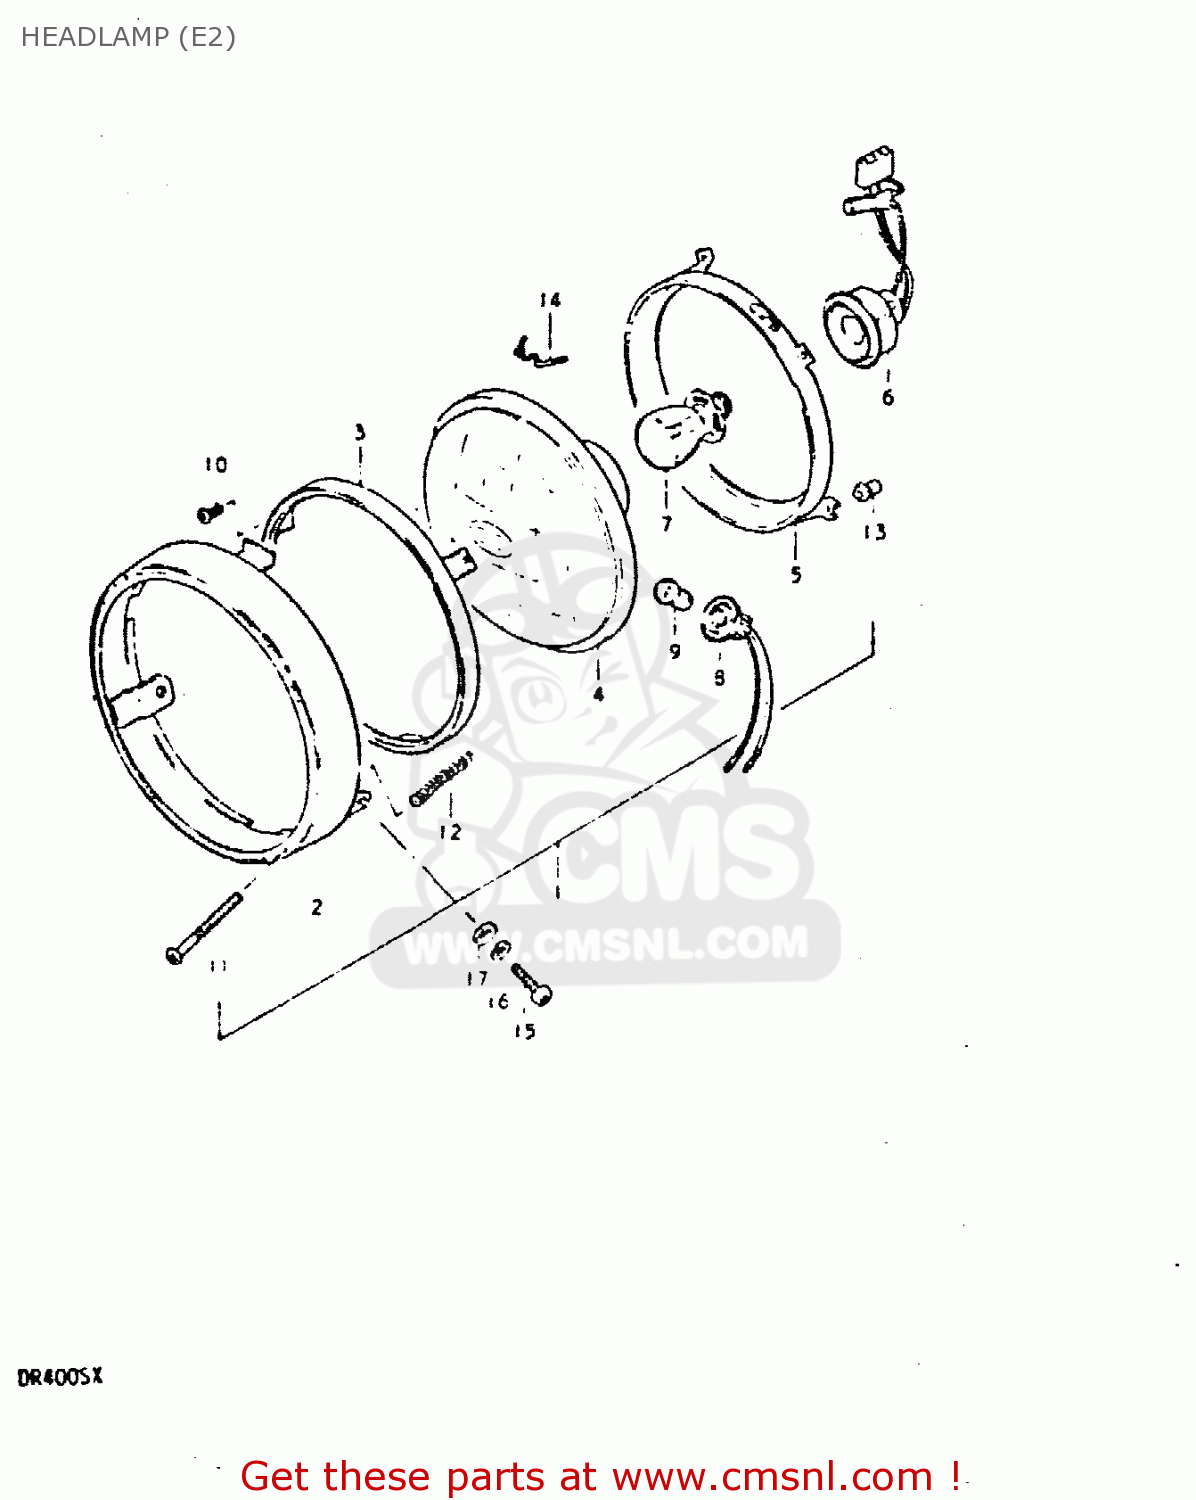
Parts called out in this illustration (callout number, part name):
1	HEADLAMP ASSY
2	RIM
3	RETAINER,HEADLAMP
4	UNIT
5	RING, MOUNTING
6	SOCKET
7	BULB(6V,35/35W)
8	SOCKET
9	BULB(6V/3W)
10	SCREW
11	SCREW,HEADLAMP ADJUST
12	SPRING,ADJUSTING
13	NUT,HEADLAMP ADJUSTER
14	SPRING,HEADLAMP UNIT
15	SCREW
16	LOCK WASHER
17	WASHER
